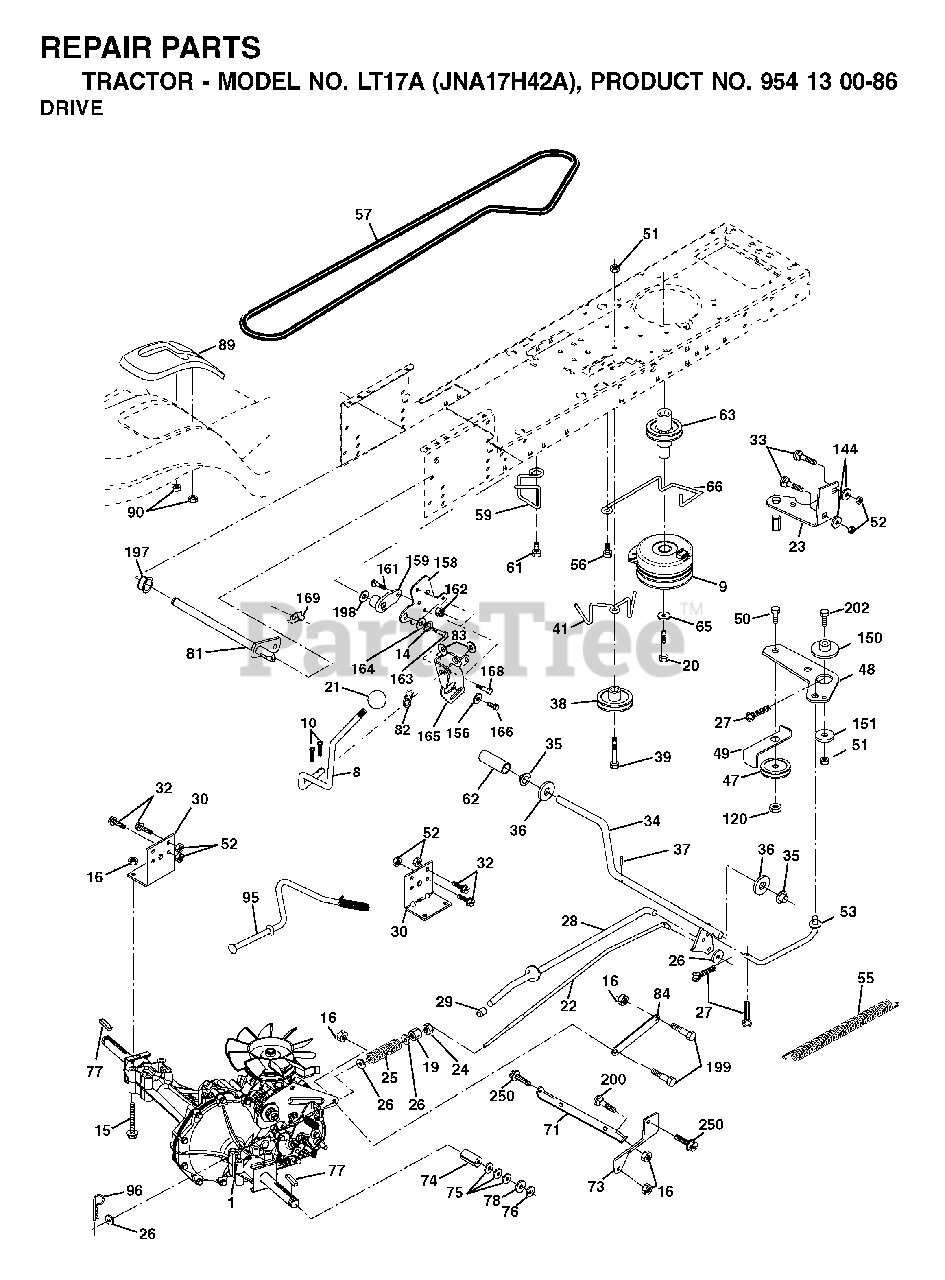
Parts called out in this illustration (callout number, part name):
8	ROD SHIFT FENDER ADJUST STLT
9	CLUTCH, ELECTRIC
10	PIN COTTER
14	LOCKWASHER
15	BOLT HEX 5/16-18 GR 5
16	NUT.71038.31-18.HEX.NYLOCK
19	NUT
20	BOLT HEX
21	PISTOL KNOB
22	ROD BRAKE HYDRO
24	NUT
25	SPRING ROD LT
27	COTTER PIN
28	ROD, PARKING BRAKE
29	PLUNGER CAP
30	BRKT, TRNSXLE MNT 20"
32	BOLT
33	BOLT
34	SHAFT, FOOT PEDAL
35	BEARING.NYLON
36	WASHER LT
37	DRIVE PIN
38	PULLEY IDLER COMPOSITE
39	BOLT
41	KEEPER, BELT IDLER
47	IDLER PULLEY
48	BELLCRANK, CLUTCH
49	RETAIN BELT
50	BOLT
51	LOCKNUT
52	LOCKNUT
53	LINK, CLUTCH LT
55	SPRING, RETURN LT
56	SCREW.3/8-16
57	DRIVE BELT, LTH & YTH TRACTORS
59	KEEPER, BELT CENTER
61	SCREW 3/8-16X.875
62	PEDAL COVER T
63	PULLEY, ENGINE
65	LOCKWASHER
66	KEEPER BELT ENGINE
71	STRAP TORQUE LH HYDRO
73	STRAP TORQUE RH HYDRO
74	SPACER AXLE
76	E-RING LT
77	SQUARE KEY
81	SHAFT ASM CROSS TAPERED
82	SHIFT SPRING
83	WASHER
84	LINK TRANSAXLE
95	CONTROL ASM. BYPASS HYDRO
96	RETAINER M
120	NUT LOCK FLG 3/8-16 UNC
144	WASHER
150	SPACER, RETAINER
151	WASHER 12/32X2X10GA
156	WASHER.SRRTD.5/16
158	BRACKET
159	HUB
161	BOLT
162	NUT.CROWNLOCK.1/4
163	BOLT
165	RP BRACKET
168	BOLT.SHOULDER.5/16-18X
169	PLATE.FASTENING.CROSS.SHAFT
197	NYLINER SNAP 5/8" ID
198	WASHER.NYL.7/8IDX.105"HYD CR
199	BOLT SHOULDER 5/16-18 UNC
200	BOLT
202	BOLT
250	SCREW 3/8-16X3/4
